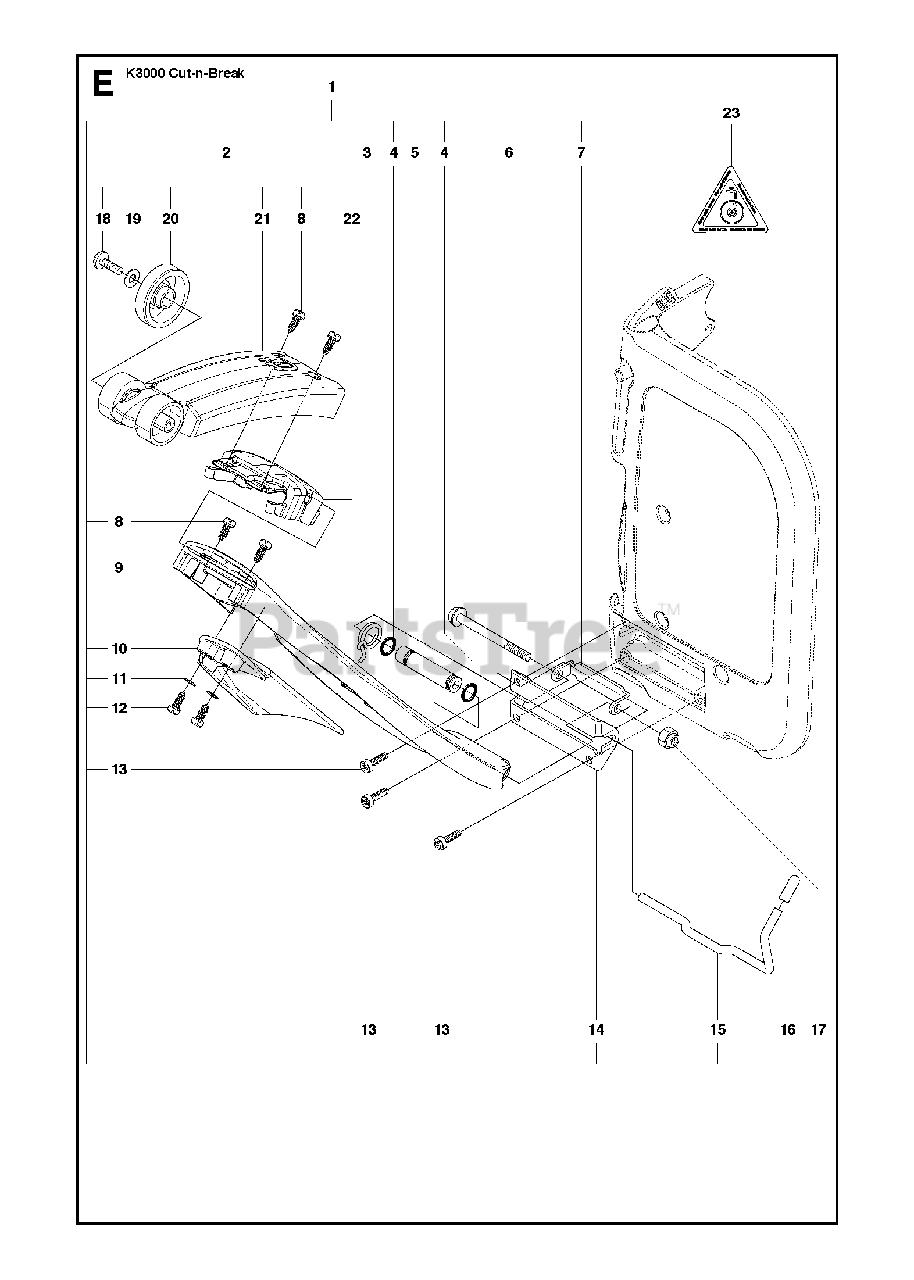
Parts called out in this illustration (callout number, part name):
1	SPRAY GUARDIncl. 2 - 17
2	SPRAY GUARDIncl. 8, 18 - 22
8	SCREW CRPANT
12	SCREW CCRPANT
13	SCREW ITXSCT
